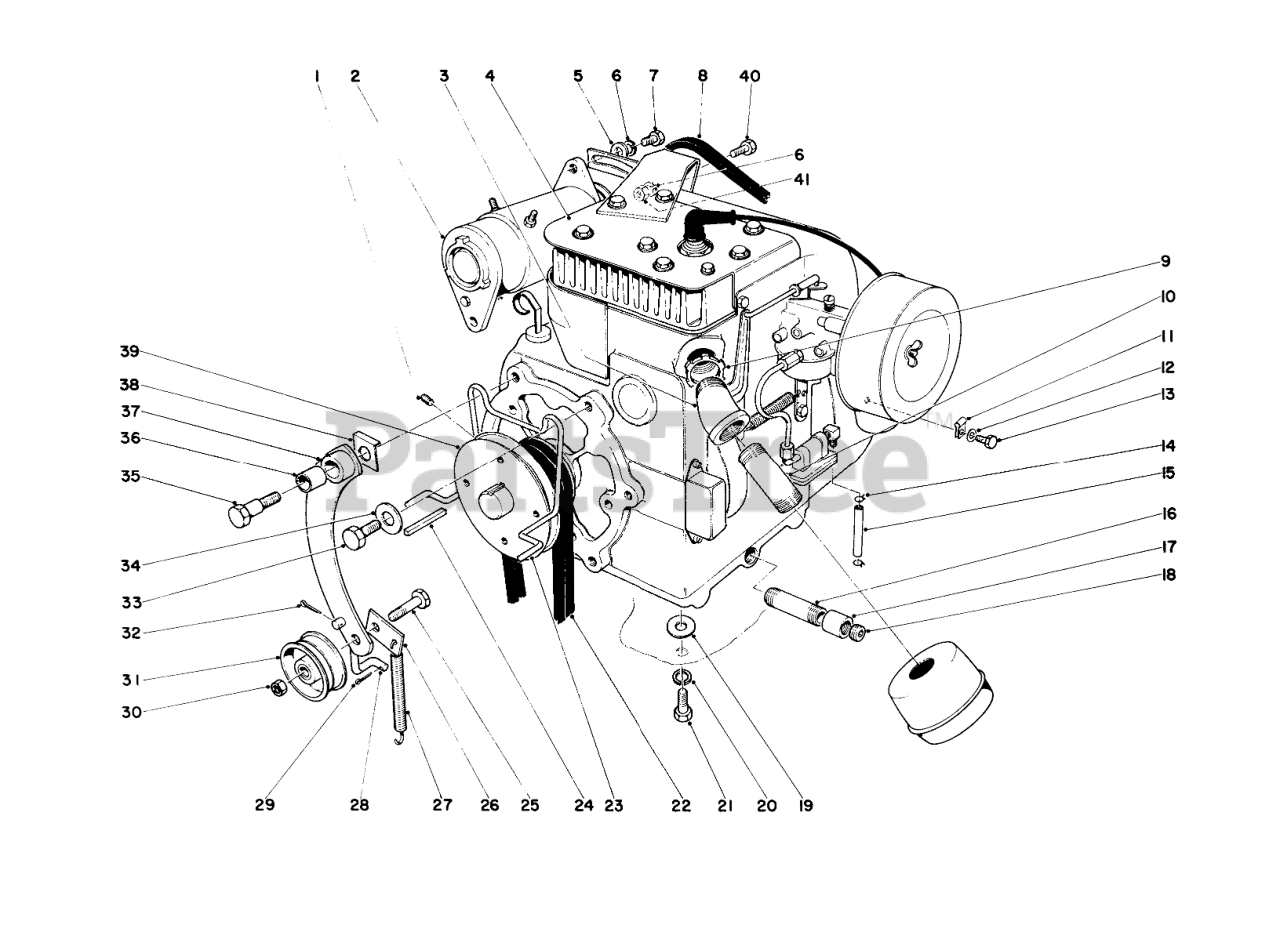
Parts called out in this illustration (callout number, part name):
1	SCREW-SET
2	Generator
3	Street Elbow
4	Engine 950
5	WASHER-FLAT
6	WASHER-LOCK
7	SCREW-HH
8	Belt, Starter Generator
9	Locknut
10	Pipe Nipple
11	Cable Clamp
12	WASHER-FLAT
13	SCREW-HH
14	Clamp
15	Gas Hose
16	Nipple
17	Coupling
18	Pipe Plug
19	WASHER-FLAT
20	WASHER-LOCK
21	SCREW-HH
22	V-BELT MATCHED SET
23	Belt Guide
24	KEY-SQUARE
25	3/8-16 X 1-1/2 BOLT
26	Spring Tab
27	Spring
28	Idler Rod
29	PIN-COTTER
30	NUT-HEX
31	Idler Pulley
32	PIN-COTTER
33	SCREW-HH
34	WASHER-FLAT
35	Shoulder Bolt
36	.503ID X .875LG BSHG
37	Idler Arm
38	Clip Belt Guide
39	Pulley Engine
40	SCREW-HH
41	NUT-HEX
